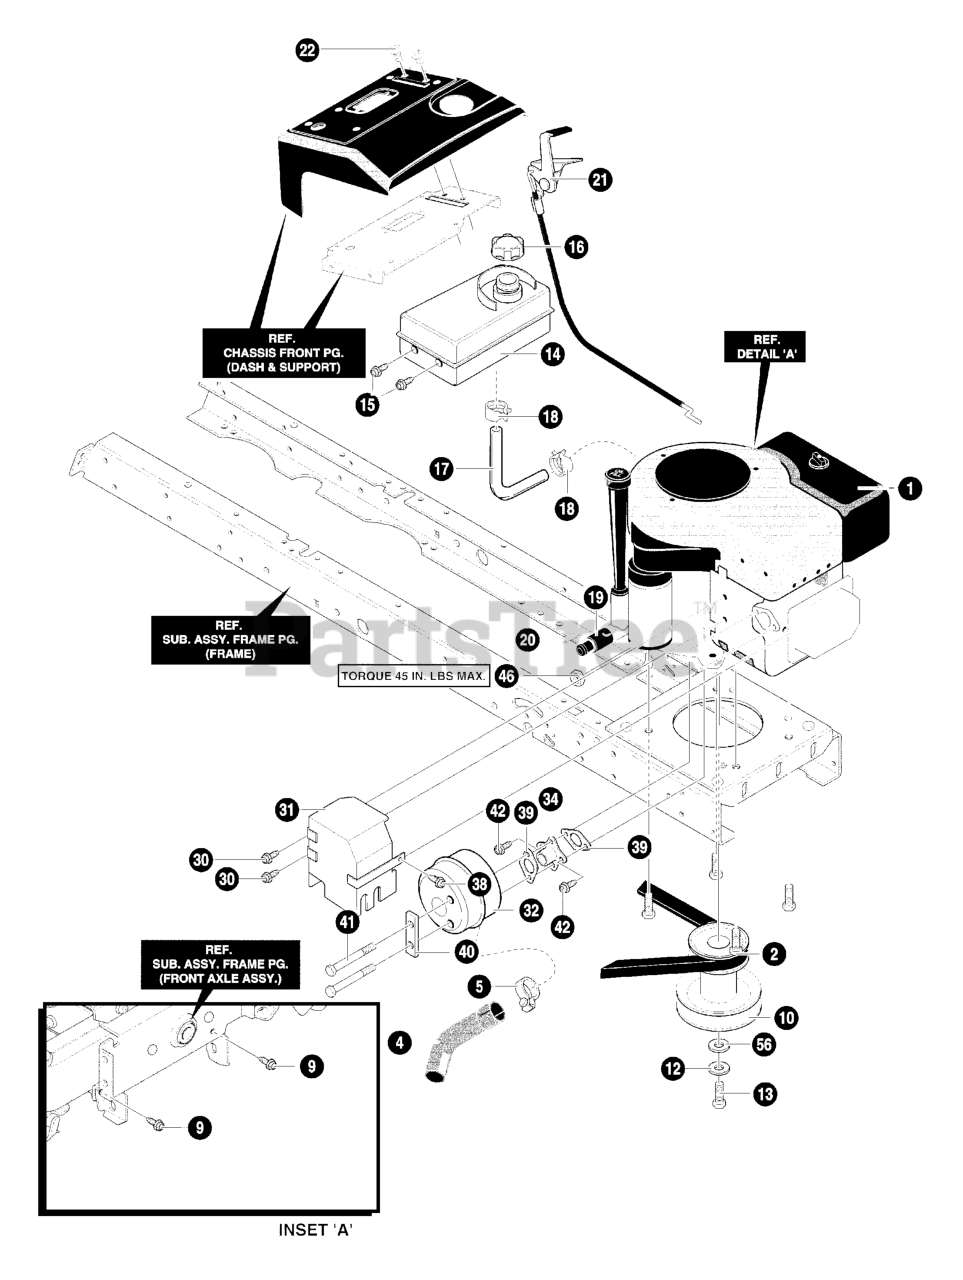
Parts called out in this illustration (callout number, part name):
1	16.5HP ENGINE
2	BOLT
4	PIPE, EXHAUST
5	CLAMP ASSEMBLY
10	STACK PULLEY ASSY.
12	WASHER
14	FUEL TANK
16	FUEL CAP
17	TUBING, GAS
18	CLAMP, FUEL LINE
19	OIL DRAIN VALVE ASSEMBLY
20	CAP, OIL DRAIN VALVE ASSY
21	THROTTLE CONTROL
31	HEAT SHIELD ASSY.
31-1	SHIELD HEAT
31-2	RIVET POP
31-3	BRACKET, HEAT SHIELD RT
31-4	BRACKET, HEAT SHIELD LH
31-5	PLATE, HEAT SHIELD
32	MUFFLER, ROUND
34	MUFFLER ADAPTER
38	SCREW, 1/4-20X.63
39	GASKET, Exhaust
40	BRACKET, LOCK
41	BOLT, 5/15-18X3.58
42	SCREW, 5/16-18 x 0.625
46	NUT, 1/4-20
56	WASHER, FLAT
